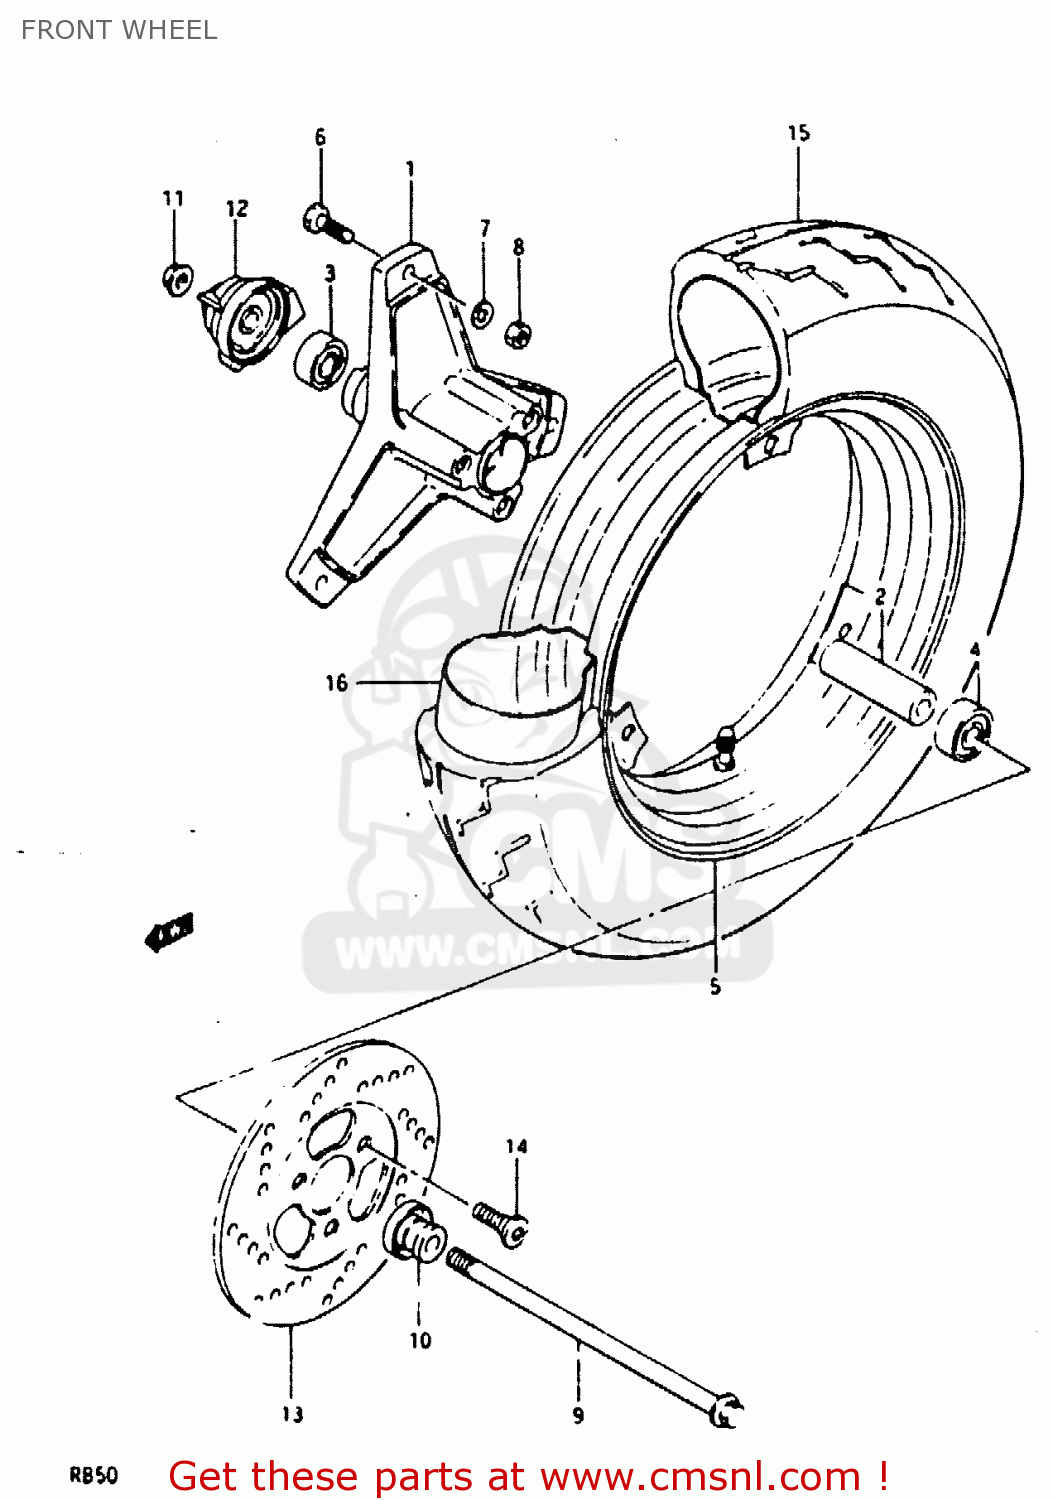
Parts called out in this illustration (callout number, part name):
1	HUB,FRONT WHEEL
2	SPACER (10.2X16X80.5)
3	BEARING
4	BEARING
5	WHEEL,RIM
6	BOLT(8X21.5)
7	LOCK WASHER
8	NUT
9	AXLE,FRONT
10	SPACER,FRONT AXLE
11	NUT
12	BOX ASSY,SPEEDOMETER GEAR
13	DISC,BRAKE
14	BOLT,BRAKE DISC
15	TIRE,FRONT 3.50-10-2P
16	TUBE,INNER
